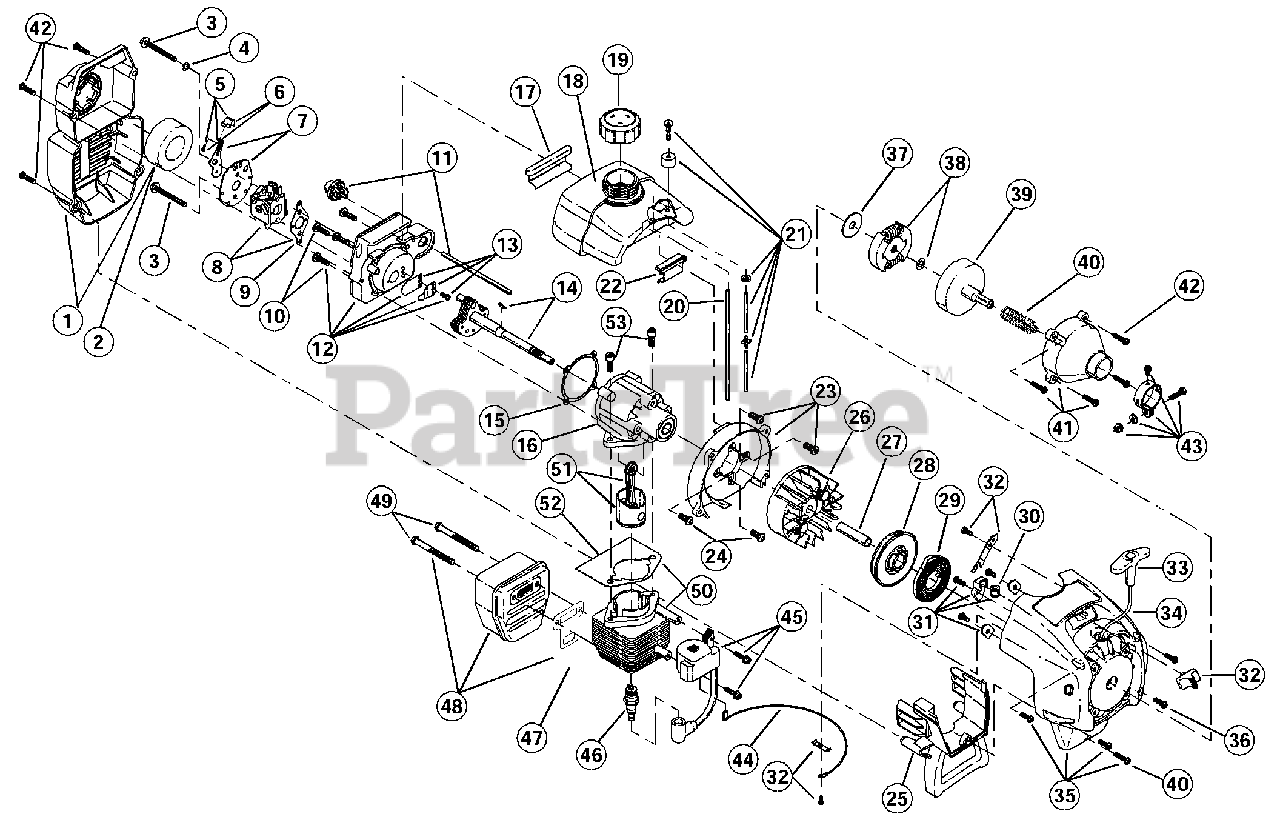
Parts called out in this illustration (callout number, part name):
1	Air Cleaner/Muffler Cover Assembly
2	Air Cleaner Filter
3	Carburetor Mounting Screw Assembly
4	Wavey Washer
5	Choke Lever Assembly
6	Choke Knob and Screw
7	Choke Lever and Plate
8	Carburetor Assembly
9	Carburetor Gasket
10	Carb Mount Screw
11	Primer and Hose Assembly
12	Carb Mount Assembly
13	Reed Assembly
15	Carburetor Mount Gasket
16	Crank Case Service Assembly
17	Rear Mounting Pad
18	Fuel Tank Assembly
19	Fuel Cap Assembly
20	Fuel Return Line
21	Fuel Line Assembly
22	Front Mounting Pad
23	Shroud Assembly
24	Shroud Screw
25	Shroud Extension & Stand
26	Flywheel Assembly
28	Recoil Pulley Assembly
29	Recoil Spring
30	Rope Guide
31	Pulley Retainer Assembly
32	Switch Assembly
33	Pull Handle
35	Starter Housing Assembly
36	Housing Screw
37	Clutch Washer
38	Clutch Rotor Assembly
39	Clutch Drum Assembly
41	Clutch Cover Assembly
42	Cover Screw
43	Upper Clamp Assembly
44	Wire Lead
45	Module Assembly
46	Spark Plug
47	Exhaust Gasket
48	Muffler Assembly
49	Muffler Mounting Bolt Assembly
50	Cylinder Assembly
51	Piston and Rod Assembly
52	Cylinder Gasket
53	Cylinder Bolt
